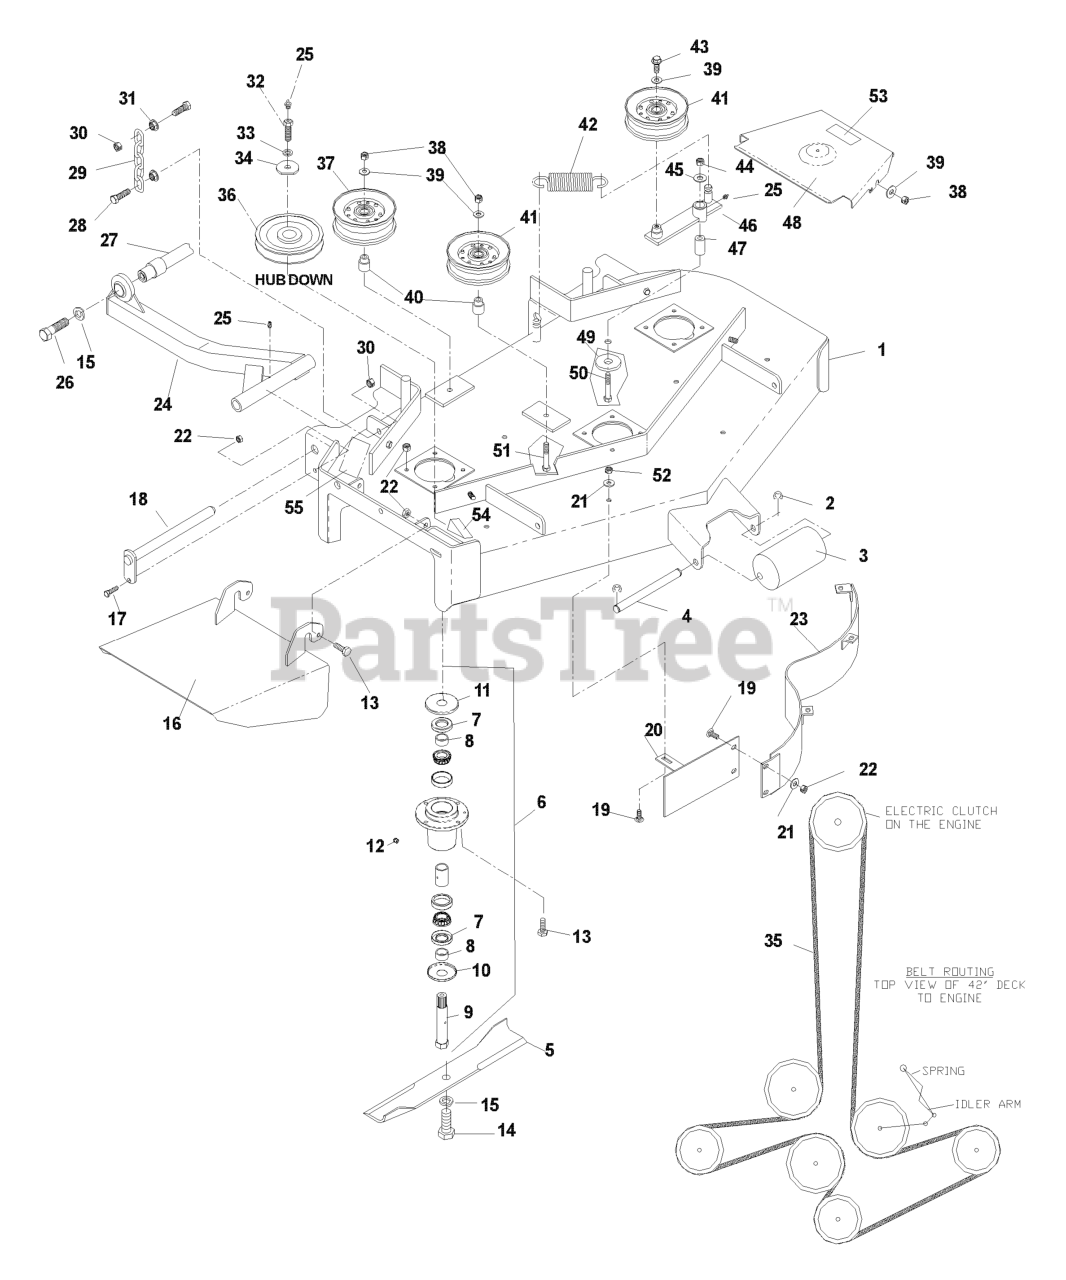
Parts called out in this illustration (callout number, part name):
1	DECK W/DECALS 42"
2	E-RING 1/2 (2 2)
5	BLADE OEM, 14-7/8
6	SPINDLE ASSY - 42/48"
7	SHAFT SEAL
9	SPLINED SHAFT - 42/48"
10	BOTTOM DUST CAP
11	TOP DUST CAP
12	PLUG-VENTED
13	HCS 5/16C X 1 1/4
14	HCS 5/8F X 1 1/4
15	LOCKWASHER 5/8
16	DISCHARGE CHUTE 42"
17	HCS 5/16C X 3/4
19	CARRIAGE BOLT 5/16C X 5/8"
20	CENTER BAFFLE
21	WASHER 5/16 FLAT
22	NUT 5/16 NYLOC
23	MAIN BAFFLE
24	STRUT WLDMT - RT
25	ZERK
26	HCS 5/8C X 2 GR.5
27	STRUT MOUNT WELDMENT
28	HCS 7/16C X 1 1/2
29	LIFT CHAIN
30	NUT 7/16C CENTERLOCK
31	NUT 7/16C WHIZ
32	DRILLED BOLT 7/16-20 X 1 1/2"
33	WASHER 7/16 LOCK
34	SPINDLE WASHER
35	BELT, DECK 42"
36	RP PULLEY - 42/48"
37	IDLER PULLEY (TALL)
38	NUT 3/8-16 NYLOC
39	WASHER 3/8 FLAT
40	IDLER BUSHING
41	IDLER PULLEY
43	4CS 3/8C X 1 SERRATED HEAD
44	NUT 1/2-13 HEX NYLOC ZD
45	WASHER 1/2 FLAT
47	PIVOT BUSHING
48	LT 42 SHIELD
49	WASHER, SUPPORT
50	HCS 1/2C X 3 1/4
51	SCREW 3/8C X 2 3/4 HEX CAP
52	NUT 5/16C CENTERLOCK
53	DECAL, NO STEP
54	DECAL, CPSC
55	DECAL, DANGER
